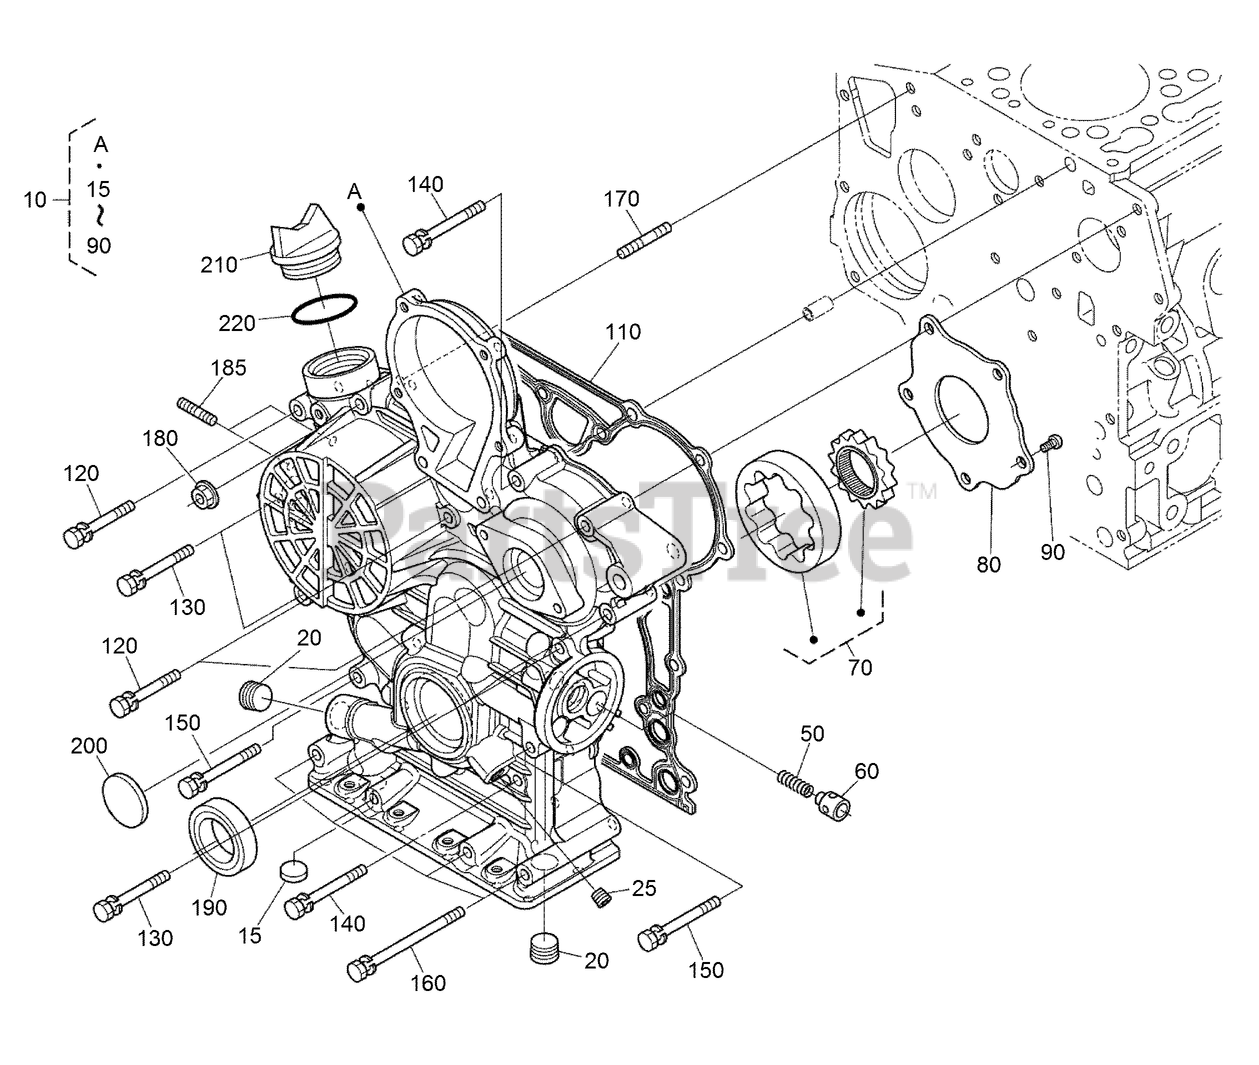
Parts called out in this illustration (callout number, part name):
10	GEAR CASE ASM
15	CAP-SEALING
50	SPRING
60	VALVE-RELIEF
70	ROTOR ASM
80	COVER-PUMP, OIL
90	SCREW-BINDING
110	GASKET-CASE, GEAR
130	BOLT-SEMS
180	NUT-FLANGE
190	SEAL-OIL
200	PLUG-GEARCASE
210	PLUG-FILLER, OIL
220	O-RING
